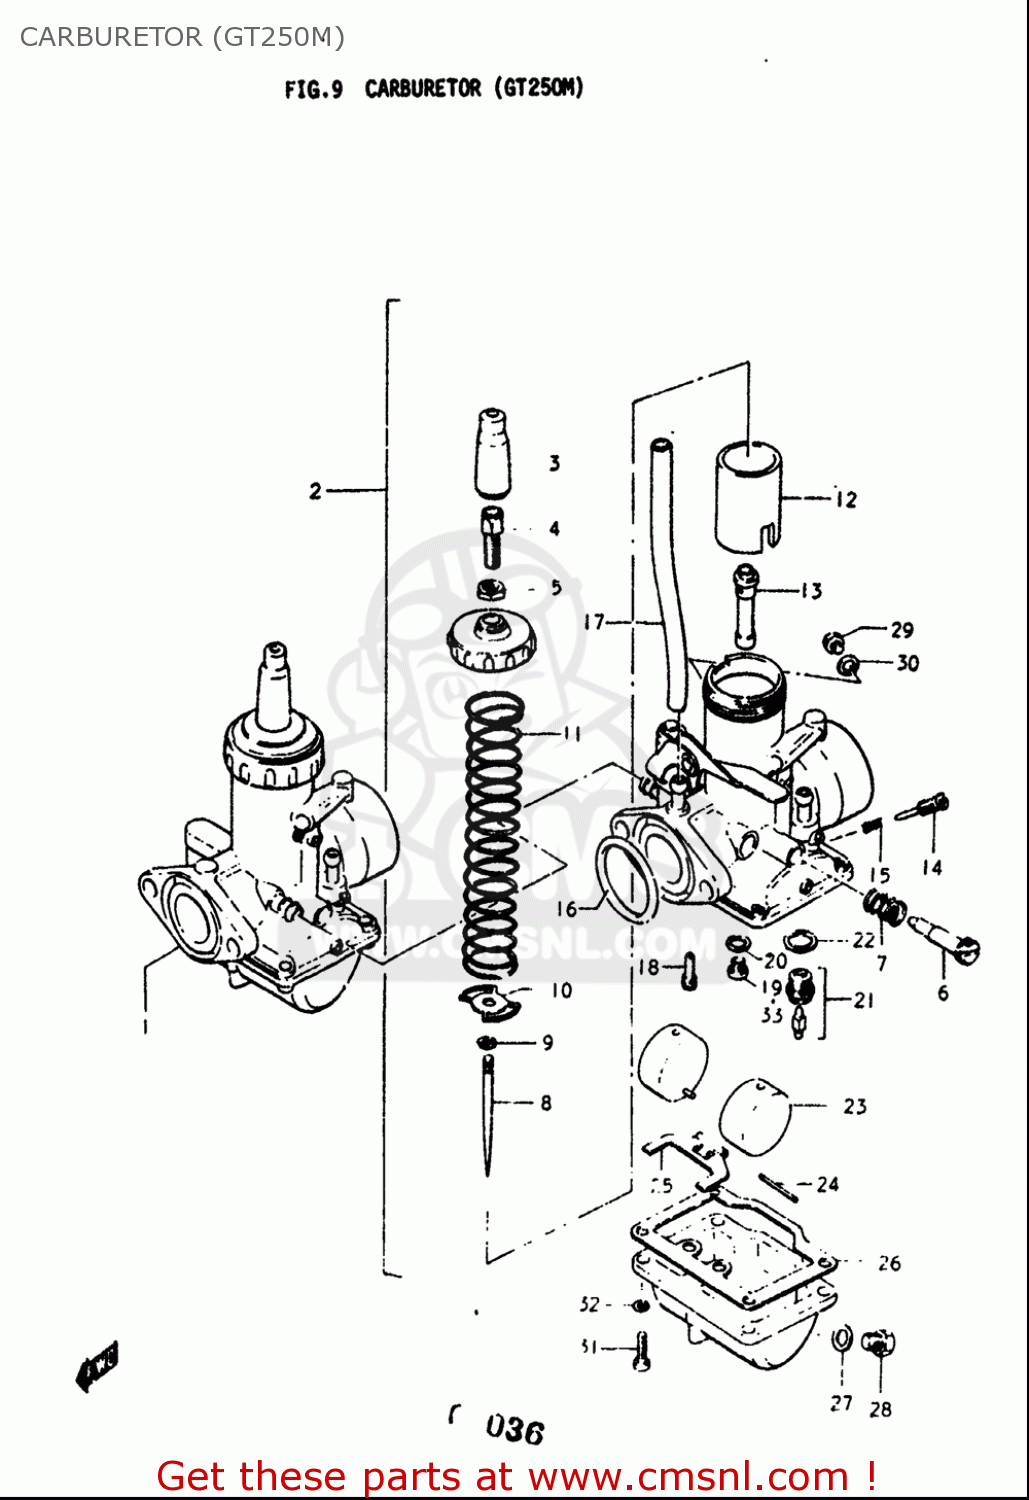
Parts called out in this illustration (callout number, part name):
3	CAP,CABLE ADJUSTER
4	ADJUSTER,CABLE
5	NUT
7	SPRING,THROTTLE SCREW
8	NEEDLE,JET(5CN3)
9	CLIP
14	SCREW,PILOT AIR
15	SPRING
17	HOSE(4.5X8.5X600)
18	JET,PILOT(25)
19	JET,MAIN(112.5)
20	WASHER
21	VALVE ASSY,NEEDLE
22	GASKET,VALVE SEAT (NAS)
23	FLOAT
24	PIN,FLOAT
26	GASKET,FLOAT CAHMBER (NAS)
27	GASKET,DRAIN,PLUG (NAS)
28	PLUG
30	GASKET,THRO VALVE INSPECTION (NAS)
31	SCREW 4X16
32	WASHER,LOCK
33	JET,MAIN(110)
